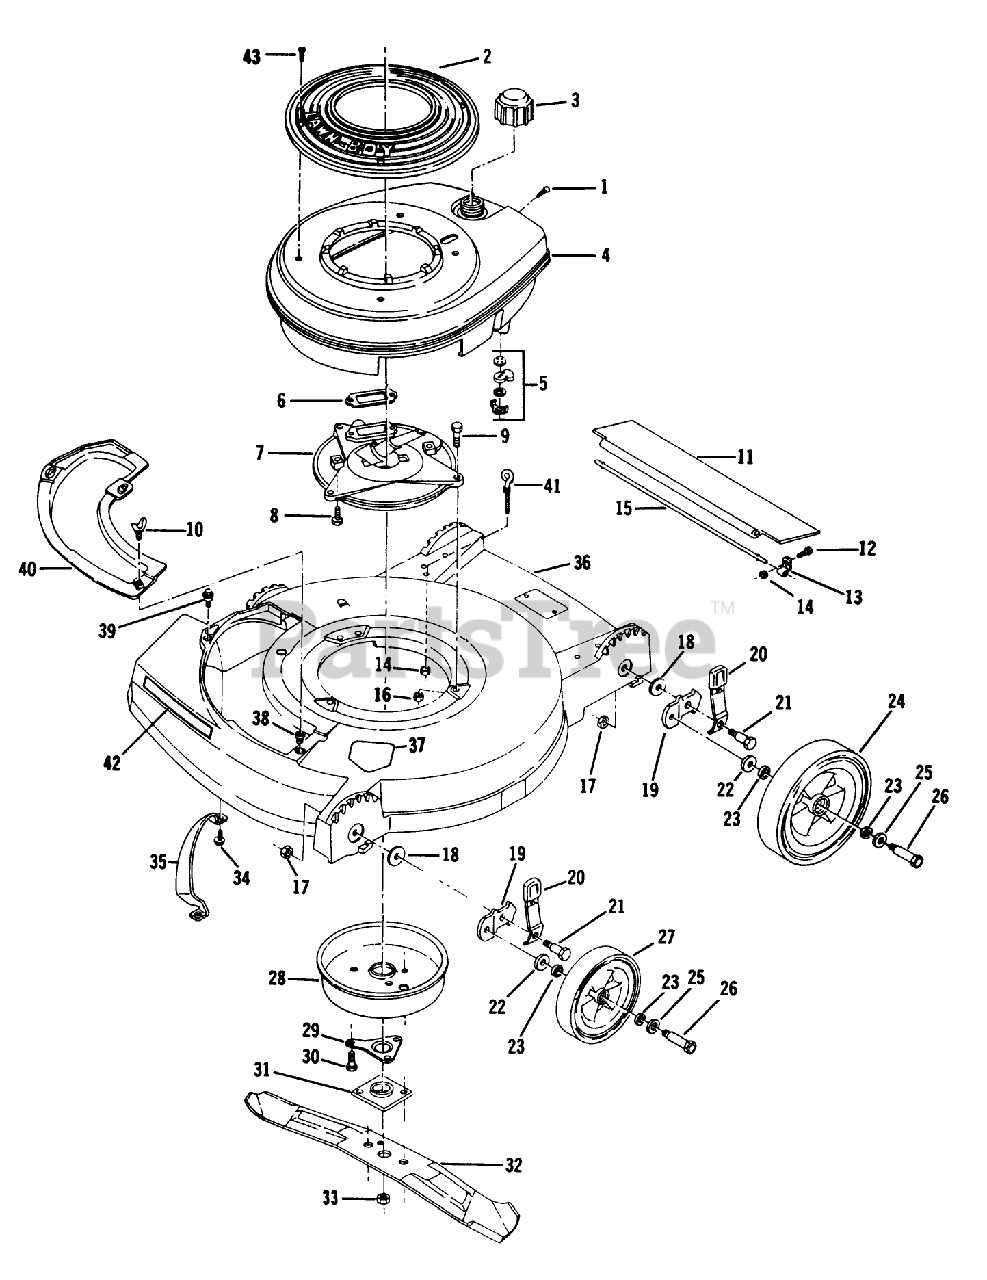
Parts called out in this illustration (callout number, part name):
1	SCREW S
3	FUEL CAP & INSERT
5	SHUT OFF VALVE KIT
7	PLATE F
8	SCREW V
9	SCREW-HH
10	WING SCREW LAWRE
13	CLAMP ROD KMC
14	LOCKNUT E
15	ROD T/SHIELD ADV WIRE
16	NUT-LOCK F
17	LOCKNUT
18	WASHER
21	BOLT
22	WASHER WROUGHT
23	WASHER
25	SPACER
26	BOLT WHEEL
27	WHEEL & TIRE KIT
28	MUFFLER COVER F
29	SUPPORT F
30	SCREW
31	PLATE AND COLLAR ASM
33	NUT-BLADE
35	TOE BAR 19"
41	BOLT-EYE
43	SCREW - SELF TAPPING
